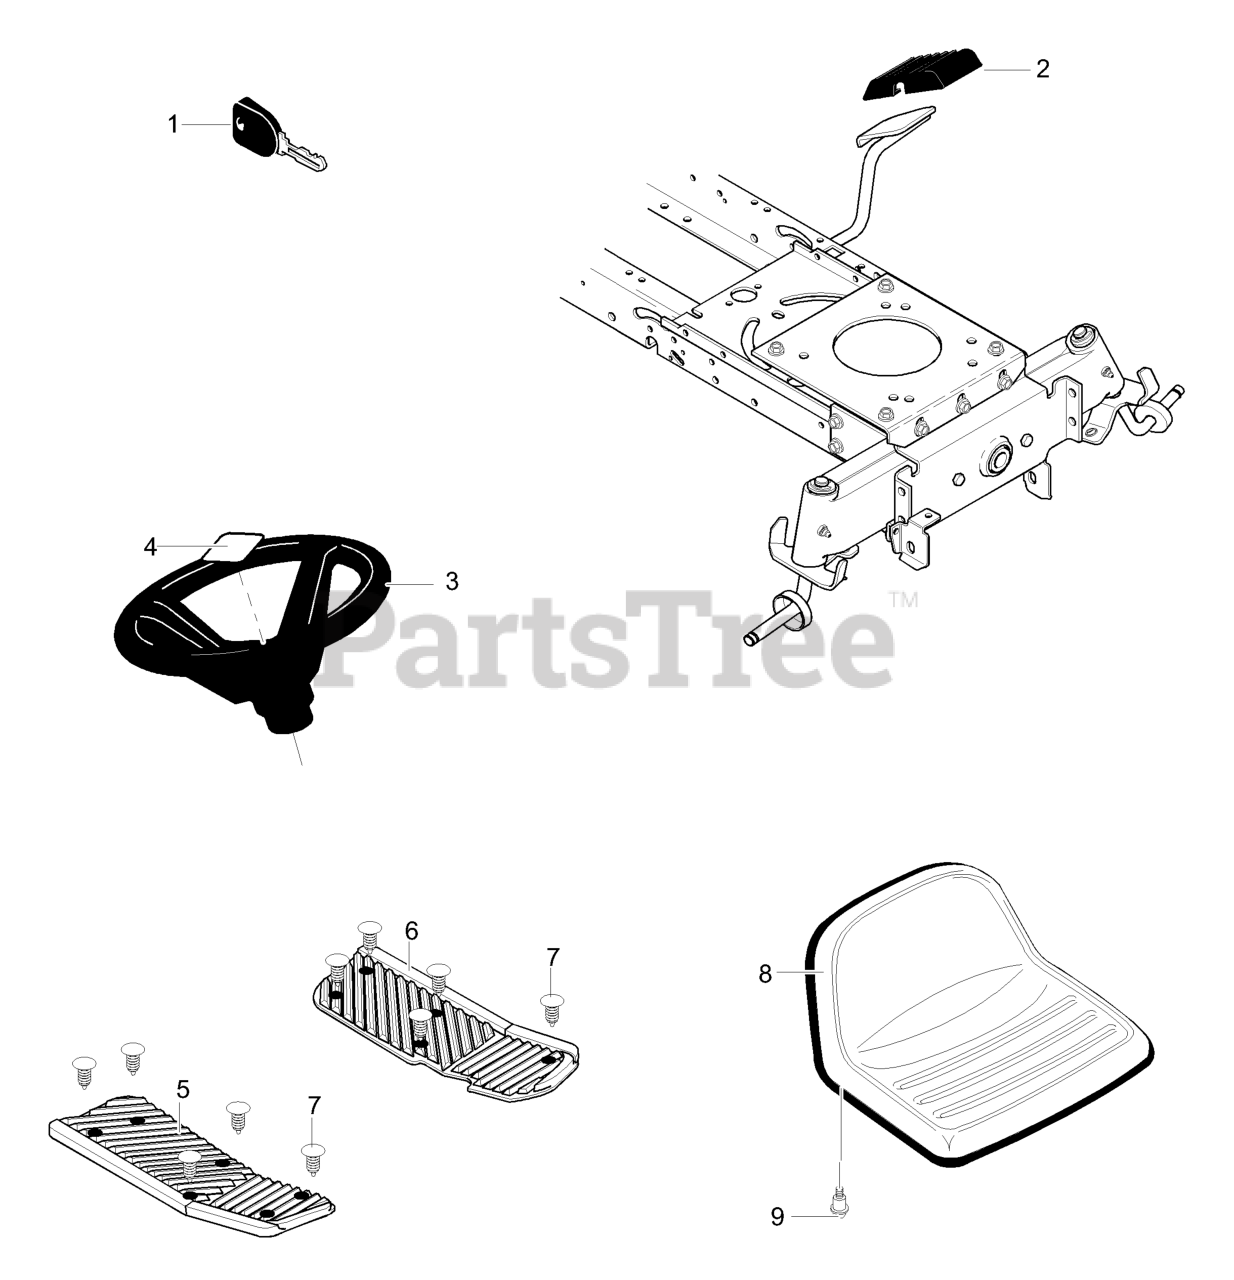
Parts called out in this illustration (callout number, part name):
1	Ignition Key
2	Pad, Clutch/Brake
3	Steering Wheel
4	Insert, 4-Spoke
5	Footrest Pad RH
6	Footrest Pad LH
7	Ratchet Fastener
9	Shoulder Bolt 5/16-18
